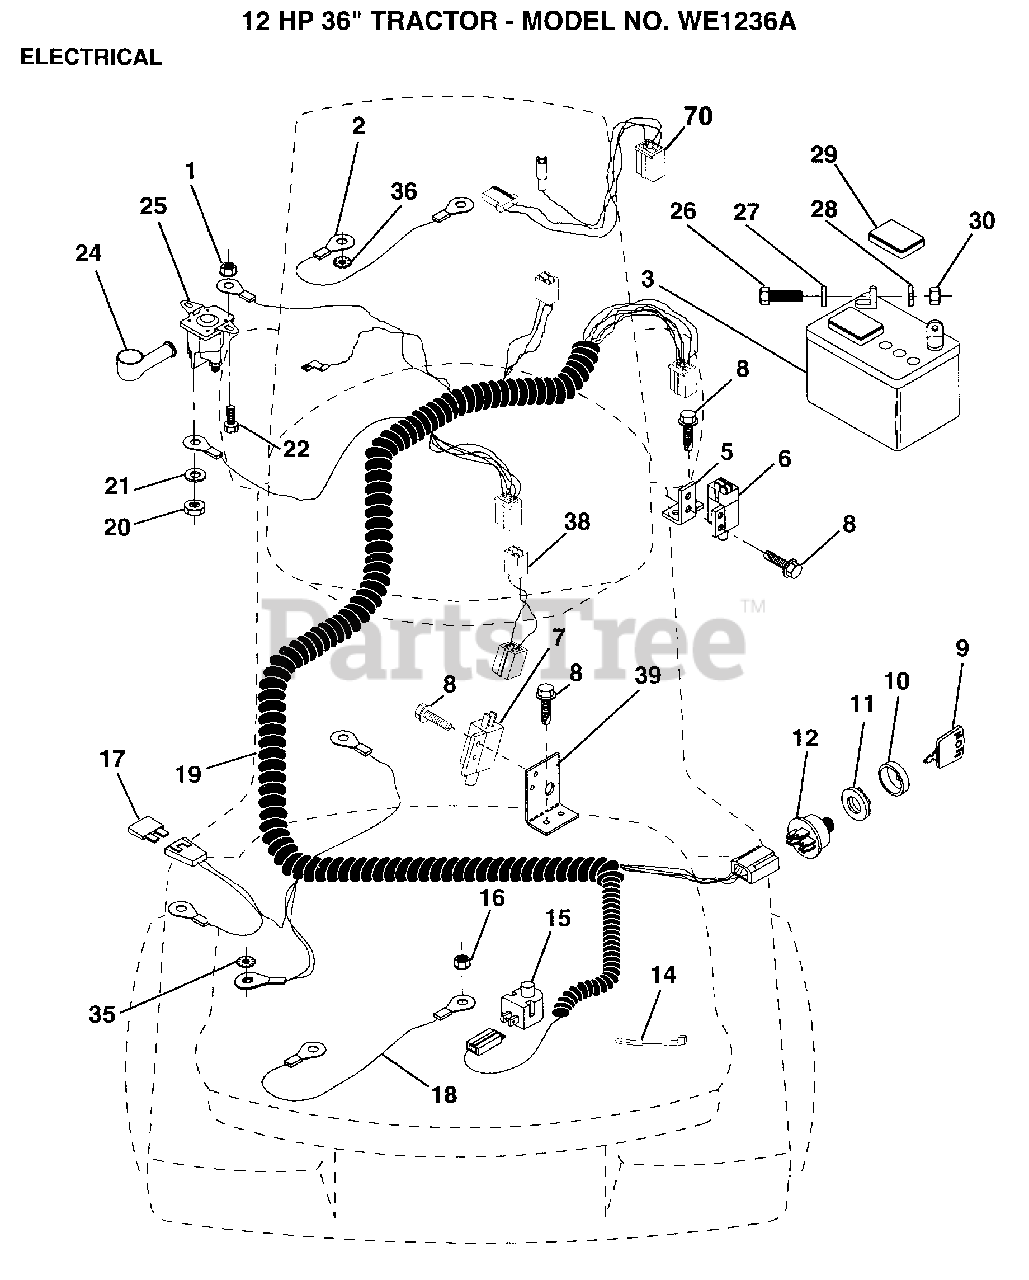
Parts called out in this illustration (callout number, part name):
1	NUT
2	CABLE ASM.
5	BRACKET LT
6	SWITCH INTERLOCKT
7	SWITCH-INTER. GT
8	SCREW
9	KEY MLD GEN DELTA
10	COVER KEY SWITCH
14	WIRE TIE
15	SWITCH SEAT
17	FUSE HYT
18	CABLE ASSY
19	HARNESS IGNITION
20	NUT
22	BOLT
26	BOLT LT
27	WASHER
28	LOCKWASHER
29	"CAP,BATTERY "
35	LOCKWASHER.5/16.E
36	LOCKWASHER
38	ADAPTER.HARN.SERV
39	BRACKET SWT CLUTC
70	HARNESS ENG DUAL
